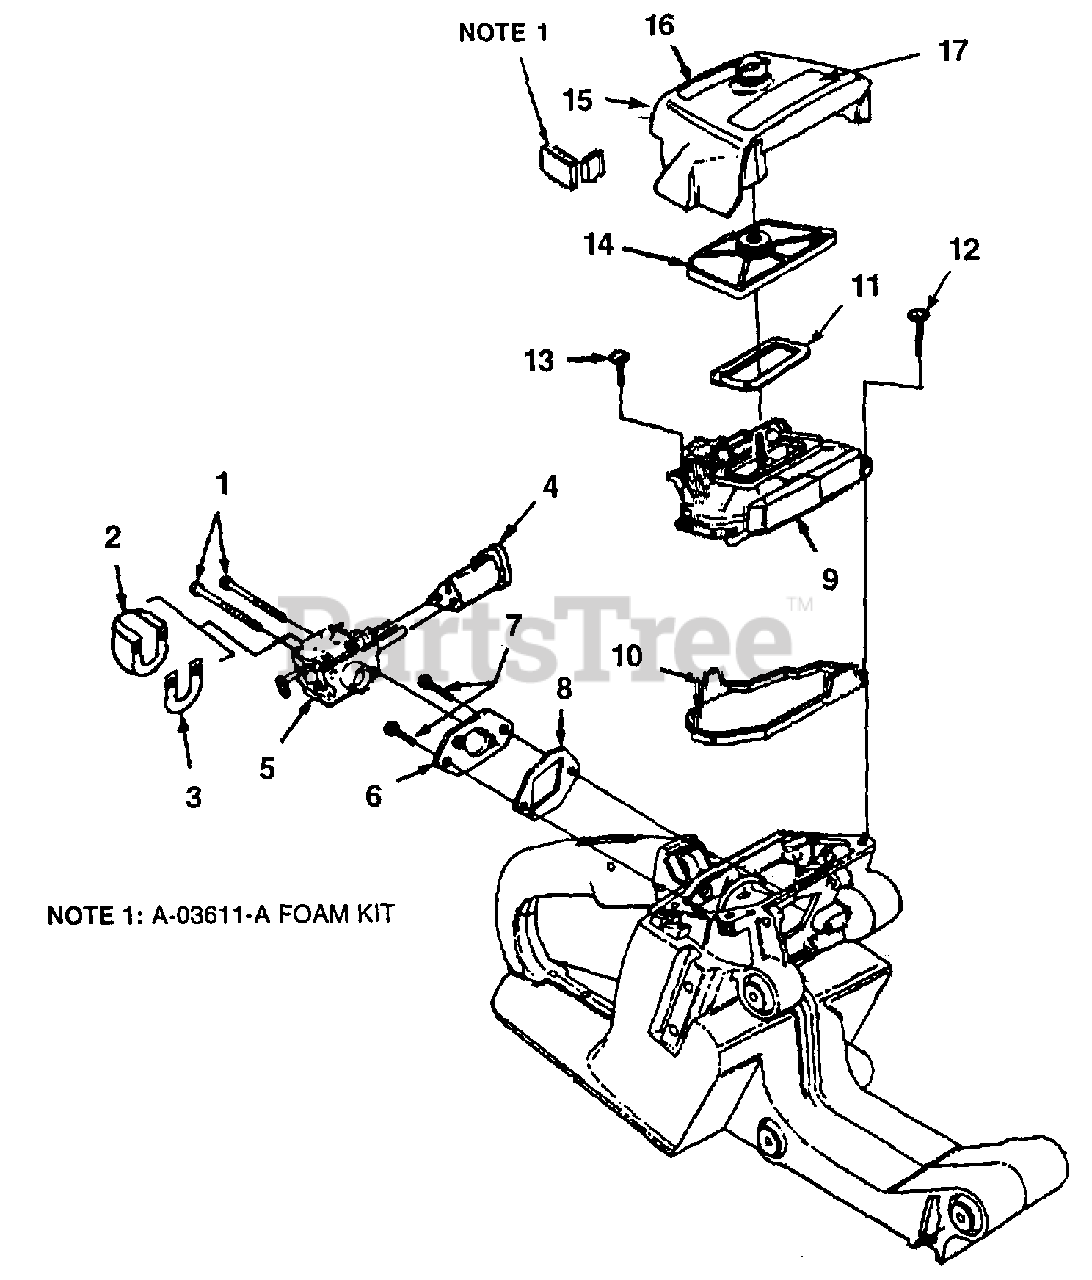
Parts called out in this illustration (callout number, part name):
1	SCREW - Hex Cap (10-24 X 2")
2	SHIELD - Carburetor
3	GASKET - Carburetor Shield
5	CARBURETOR KIT
6	ADAPTER - Carburetor
7	SCREW - Torx Truss (10-24 X 1/2")
8	GASKET - Carburetor
9	COVER - Carburetor Chamber
10	GASKET - Carburetor Chamber
11	GASKET - Air Filter
12	SCREW - Pan Hd. (8-32 X 5/8")
13	SCREW - Machine Pan Hd. (8-32 x 3/8")
14	ELEMENT - Filter
15	COVER - Air Filter
16	DECAL - Warning
17	DECAL - Warning
